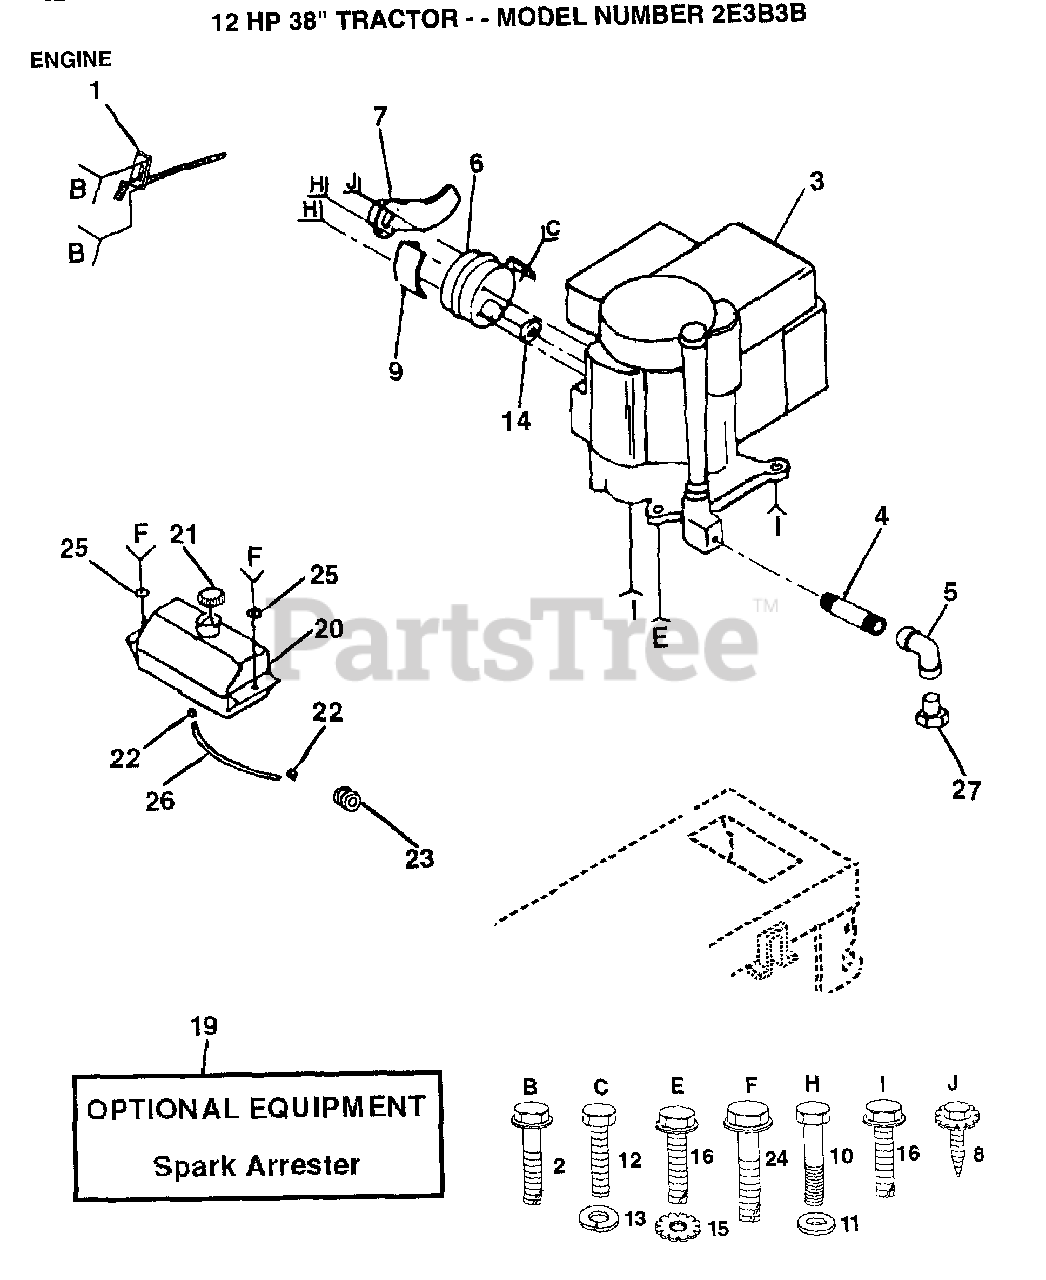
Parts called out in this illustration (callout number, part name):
1	THROTTLE CONTROL
2	SCREW LT
4	PIPE NIPPLE
5	ELBOW
6	MUFFLER LTV
7	DEFLECTOR MUFFLER
9	SHIELD HEAT LTV
10	"BOLT,HEX"
11	WASHER T
12	BOLT
13	LOCKWASHER
15	LOCKWASHER
16	SCREW
20	TANK.FUEL.LT.
21	CAP ASM FUEL
22	HOSE CLAMP
24	SCREW HEX CRT
25	WASHER
26	LINE FUEL
